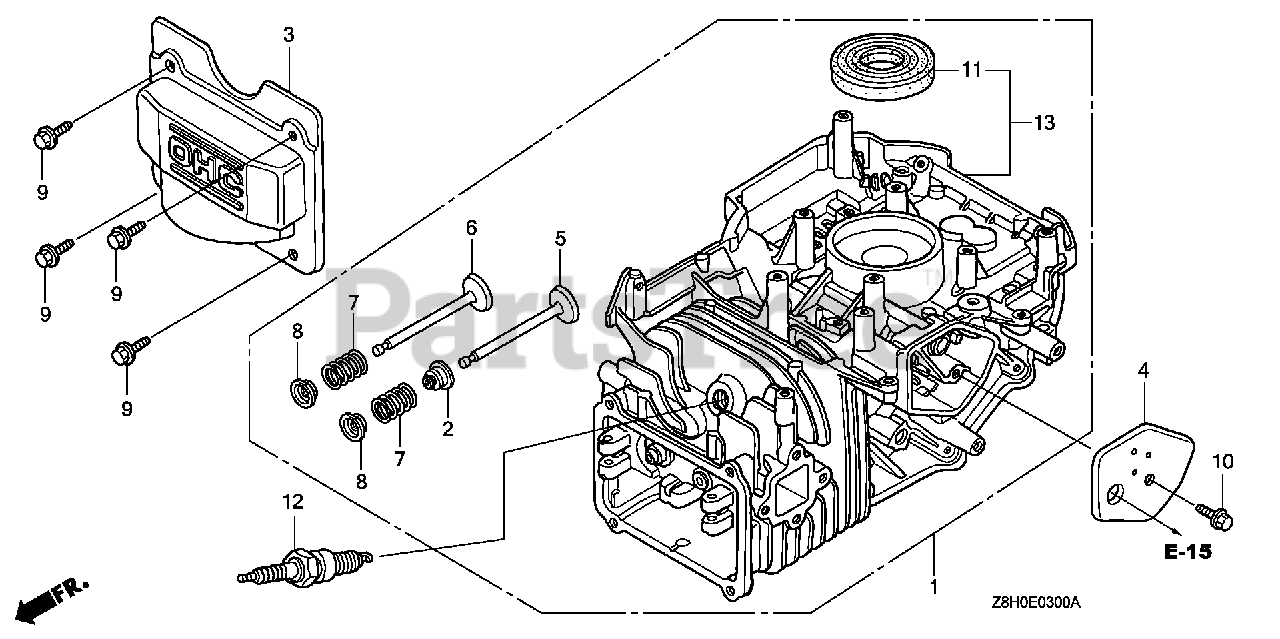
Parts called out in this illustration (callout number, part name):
2	SEAL, VALVE STEM
3	COVER, CYLINDER HEAD
4	COVER, BREATHER (BREATHER VALVE ASSY.)
5	VALVE, IN. (TECHNOSTAR)
6	VALVE, EX. (L8E)
6	VALVE, EX. (C8E)
7	SPRING, VALVE
8	RETAINER, IN. VALVE SPRING
8	RETAINER, VALVE SPRING
9	BOLT, FLANGE (6X12) (CT200)
10	BOLT, FLANGE (6X14) (CT200)
11	OIL SEAL (25.4X62X6)
12	SPARK PLUG (BPR6ES) (NGK)
13	CYLINDER ASSY.
